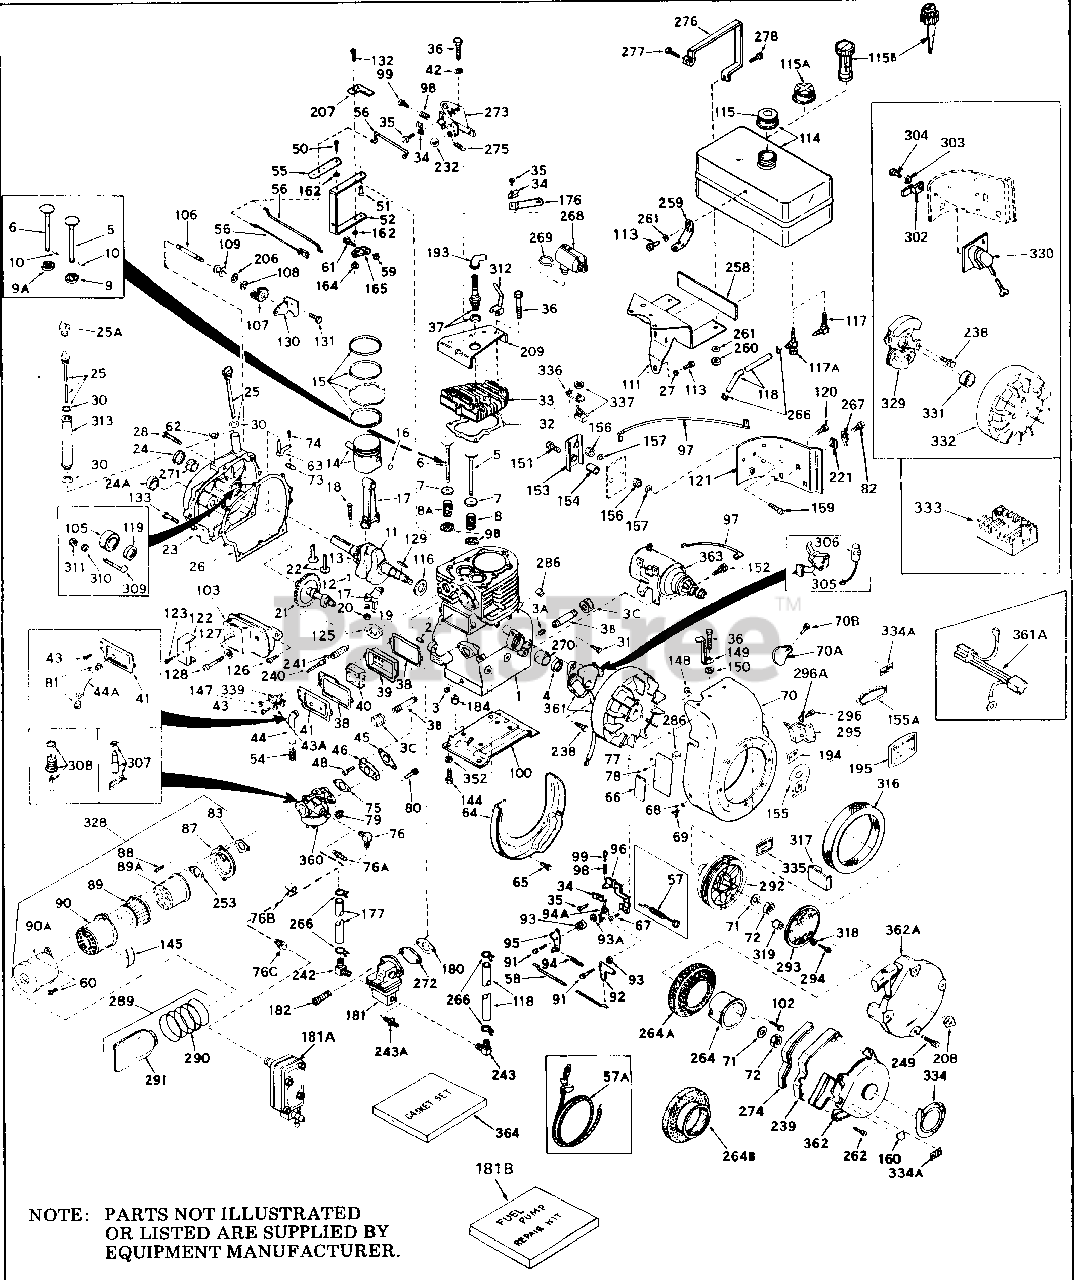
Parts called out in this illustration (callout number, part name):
1	"Cylinder Assy, (2-5/8" Bore)
2	Pin, Dowel
3	Plug, 0il drain
3A	Plug, 0il drain
4	Seal, 0il
5	Valve, Intake (Standard) (Long Life)
5	Valve, Intake (1/32" Oversize) (Long Life)
6	Valve, Exhaust (Standard) (Long Life)
6	Valve, Exhaust (1/32" Oversize) (Long Life)
7	Cap, Upper valve spring
8	Spring, Valve
9	Cap, Lower valve spring (Standard)
9	Cap, Lower valve spring (1/32" Oversi ze)
9A	Cap, Lower valve spring (Standard)
9A	Cap, Lower valve spring (1/32" Oversi ze)
9B	Cap, Lower valve spring
10	Pin, Valve spring retaining
11	Crankshaft Assy.
12	Pin, Crankshaft gear
13	Gear, Crankshaft
14	Piston & Pin Assy. (Standard) (2-5/8" )
14	Piston & Pin Assy. (.010 Oversize)
14	Piston & Pin Assy. (.020 Oversize)
15	Re-Ringing Set, Piston
15	Ring Set, Piston (Standard) (2-5/8") (Long
15	Ring Set, Piston (.010 Oversize)
15	Ring Set, Piston (.020 Oversize)
16	Ring, Piston pin retaining
17	Rod Assy., Connecting
18	Bolt, Connecting rod
19	Washer, Connecting rod bolt
21	Camshaft Assy. (Mech. compression rel ease)
22	Lifter, Valve
23	Cover, Cylinder
24	Seal, 0il
25	Dipstick, Oil
26	Gasket, Cylinder cover
27	Lockwasher
28	Screw
30	Gasket, Dipstick
32	Gasket, Cylinder head
33	Head, Cylinder
34	Clip, Conduit
36	Screw, Hex hd. cap, 5/16-18 x 2 (Grad e 8
36	Screw, Hex hd. cap, 5/16-18 x 2-1/4 ( Grade 8
36	Screw, Hex hd. cap, 5/16-18 x 2-1/2 ( Grade 8
37	Plug, Spark (Champion D-21 or equival ent)
38	Gasket, Breather cover
39	Body, Breather
40	Element, Breather
41	Cover, Valve spring
43	Screw, Hex washer hd., 10-24 x 5/8
43A	Washer
44	Tube, Breather
45	Gasket, Intake
46	Flange, Carburetor
50	Screw
51	Rivet, Split
52	Lever, Governor
54	Spring, Breather tube
55	Bracket, Adjusting
56	Link, Throttle
57	Control, Throttle
57A	Wire Assy. Boden
62	Ring, Retaining
63	Rod Assy., Governor
64	Baffle, Blower housing
66	Decal, Instruction
67	Screw, Fil. hex Sems. 10-32 x 5/8
68	Lockwasher
69	Screw, Hehd. Sems 5/16-24 x 3/4
70	Housing, (5.56 Dia. starter mtg. bolt
71	Washer, Belleville
72	Nut, Hex
73	Yoke, Governor
75	Gasket, Carburetor (1/8" thick)
77	Plate, Identification
78	Stud, Drive
79	Nut, Lock
80	Screw
83	Gasket, Air cleaner
88	Screw, Fil. hd. Sems, 10-32 x 1/2
88	Screw, Fil. hd. Sems, 10-32 x 5/8
98	Spring, Compression
99	Screw, Fil. hd. mach., Sems, 8-32 x 3 /4
99	Screw, Fil. slotted hd. Sems, 8-32 x 5/8
99	Screw, Hex hd. 10-32 x 1-5/16 (Drille d thru)
100	Base, Mounting
105	Bearing, Ball
106	Shaft, Mechanical governor
108	Ring, Retaining
109	Spool, Governor
111	Bracket, Fuel tank
113	Screw
114	Tank Assy., Fuel (1 gal.)
115	Cap, Fuel filler (Kerosene)
115	Cap, Fuel filler (Plastic) (Standard)
115	Cap, Fuel filler (Plastic)
115A	Cap, Fuel filler (Sno-Proof)
117A	Valve, Fuel shut-off
118	Line, Fuel (Braided hose) (8.25")
118	Line, Fuel (Braided hose) (16")
118	Line, Fuel (Braided hose) (32")
119	Washer, Thrust
120	Screw
121	Extension, Blower housing
125	Gasket, Exhaust
126	Screw
127	Washer, Flat
128	Screw, Hex hd. cap, 5/16-18 x 2
129	Key, Flywheel
130	Bracket, Governor
132	Screw, Hex slotted washer hd., 8-32 x 1/2
132	Screw
133	Screw, Hex hd. cap, Sems, 1/4-20 x 1- 1/2
144	Screw, Hex hd. cap, 5/16 18 x 13/16
145	Decal, Air cleaner
149	Clip, Shorting
150	Lockwasher
152	Screw
153	Cover, Panel
155	Decal, Name & H.P, (6 H.P.)
155	Decal, Name & H.P. (5 H.P.)
155	Decal, Name & H.P, (4 H.P.)
157	Lockwasher
160	Decal, Ezee start
162	Lockwasher
164	Nut & Lockwasher
165	Clamp, Governor lever
176	Bracket, Choke control
177	Line, fuel (Braided hose) (8-1/4")
182	Screw
184	Pin, Dowel
194	Decal, H.P. (4.0 H.P.)
194	Decal, H.P, (5.0 H.P.)
194	Decal, H.P. (6.0 11.P.)
206	Washer, Flat
209	Cover, Cylinder head
232	Knob, Seed control
232	Knob, Speed control
253	Spacer, Cleaner
260	Nut, Lock
261	Washer, Flat
264	Cup, Starter
264A	Screen, Starter cup
266	Clamp, Fuel line
267	Tab, Terminal
268	Cup, Spark plug
269	Clamp, Wire
270	Bushing, Crankshaft
271	Bushing, Crankshaft
272	Cover, Fuel pump pad
273	Bracket Assy., Speed control
275	Spring, Control lever
276	Strap, Fuel tank
277	Screw
278	Screw
286	Clip, Lead wire
289	Kit, Pre-cleaner
290	Spring, Pre-cleaner bag
291	Bag, Pre-cleaner
305	Contact Assy., Breaker
306	Condenser
307	Inlet Needle, Seat & Clip Assy.
309	Retainer, Bearing
311	Nut, Lock
328	Cleaner Assy., Air
335	Decal, "Long-Life"
352	Lockwasher
360	Carburetor
361	Magneto, Tecumseh
361A	Harness Assy., Adapter
362	Starter, Rewind
363	Motor, Starter (12 Volt)
364	Gasket Set
